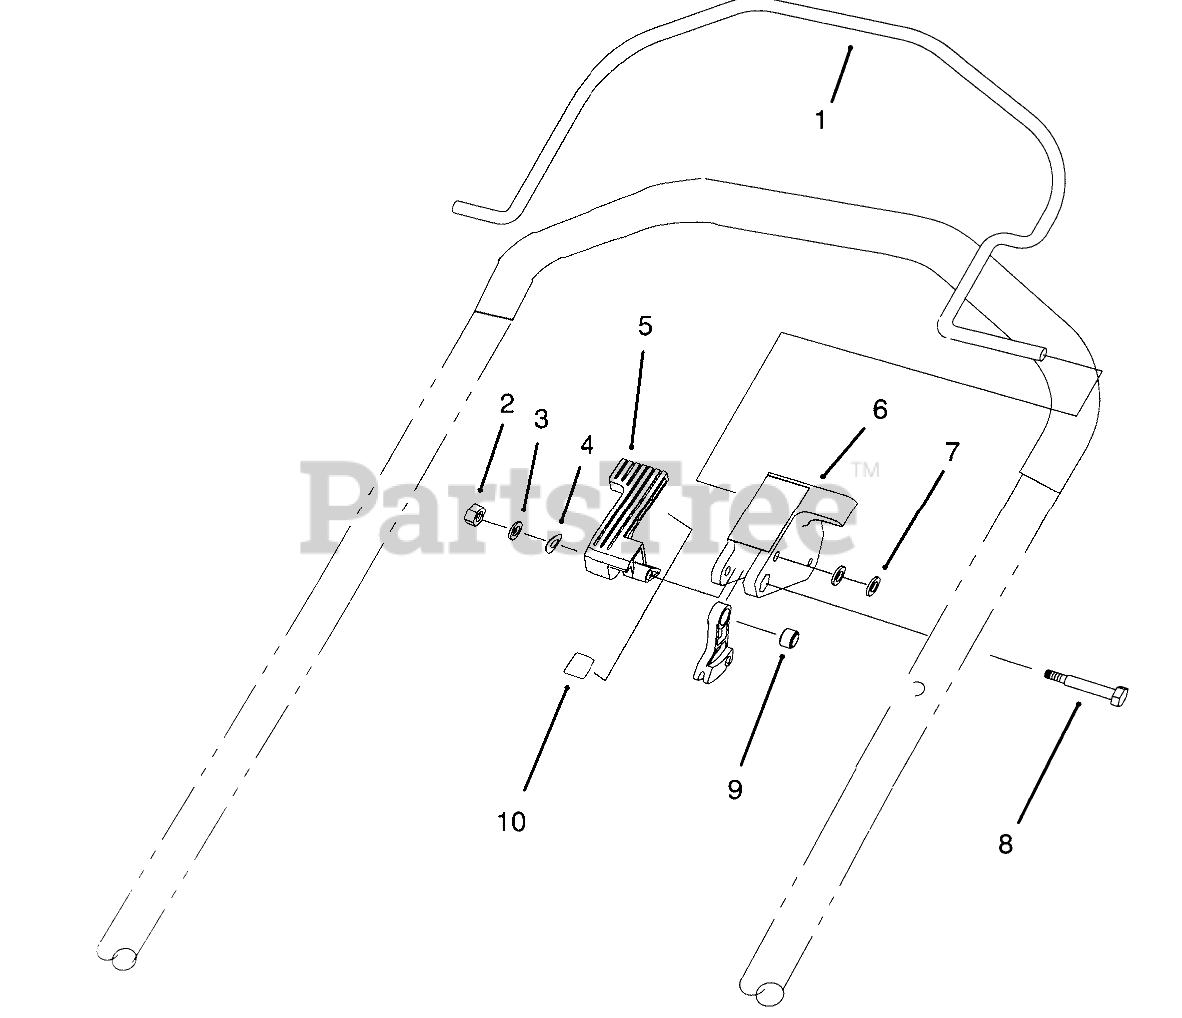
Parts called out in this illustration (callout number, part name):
1	BAIL - CONTROL
2	NUT-LOCK, NI
3	WASHER-PLAIN
4	WASHER - SPRING
5	LEVER - SHIFT
6	STOP - PIVOT, PLASTIC
7	WASHER-FLAT
8	SHOULDER BOLT
9	SPACER-LEVER, TRACTION
10	DECAL - TRACTION
